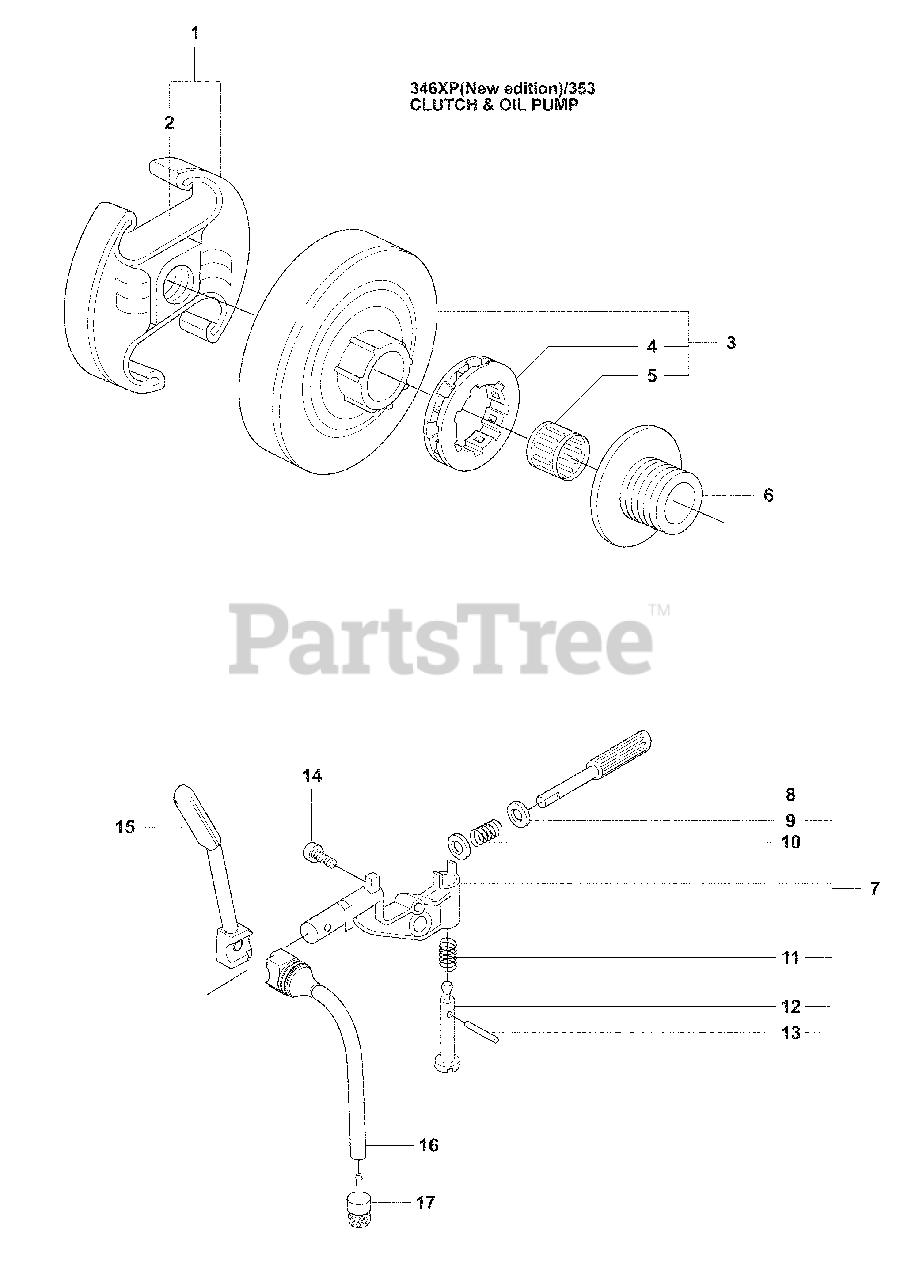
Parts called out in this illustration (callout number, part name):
3	Clutch Drum
4	Power Mate Rim
5	Needle Bearing
6	Pump Pinion
7	Oil Pump Assembly
8	Pump Piston
12	Adjuster Screw
15	Oil Pressure Hose
16	Hose
17	Oil Plummet
